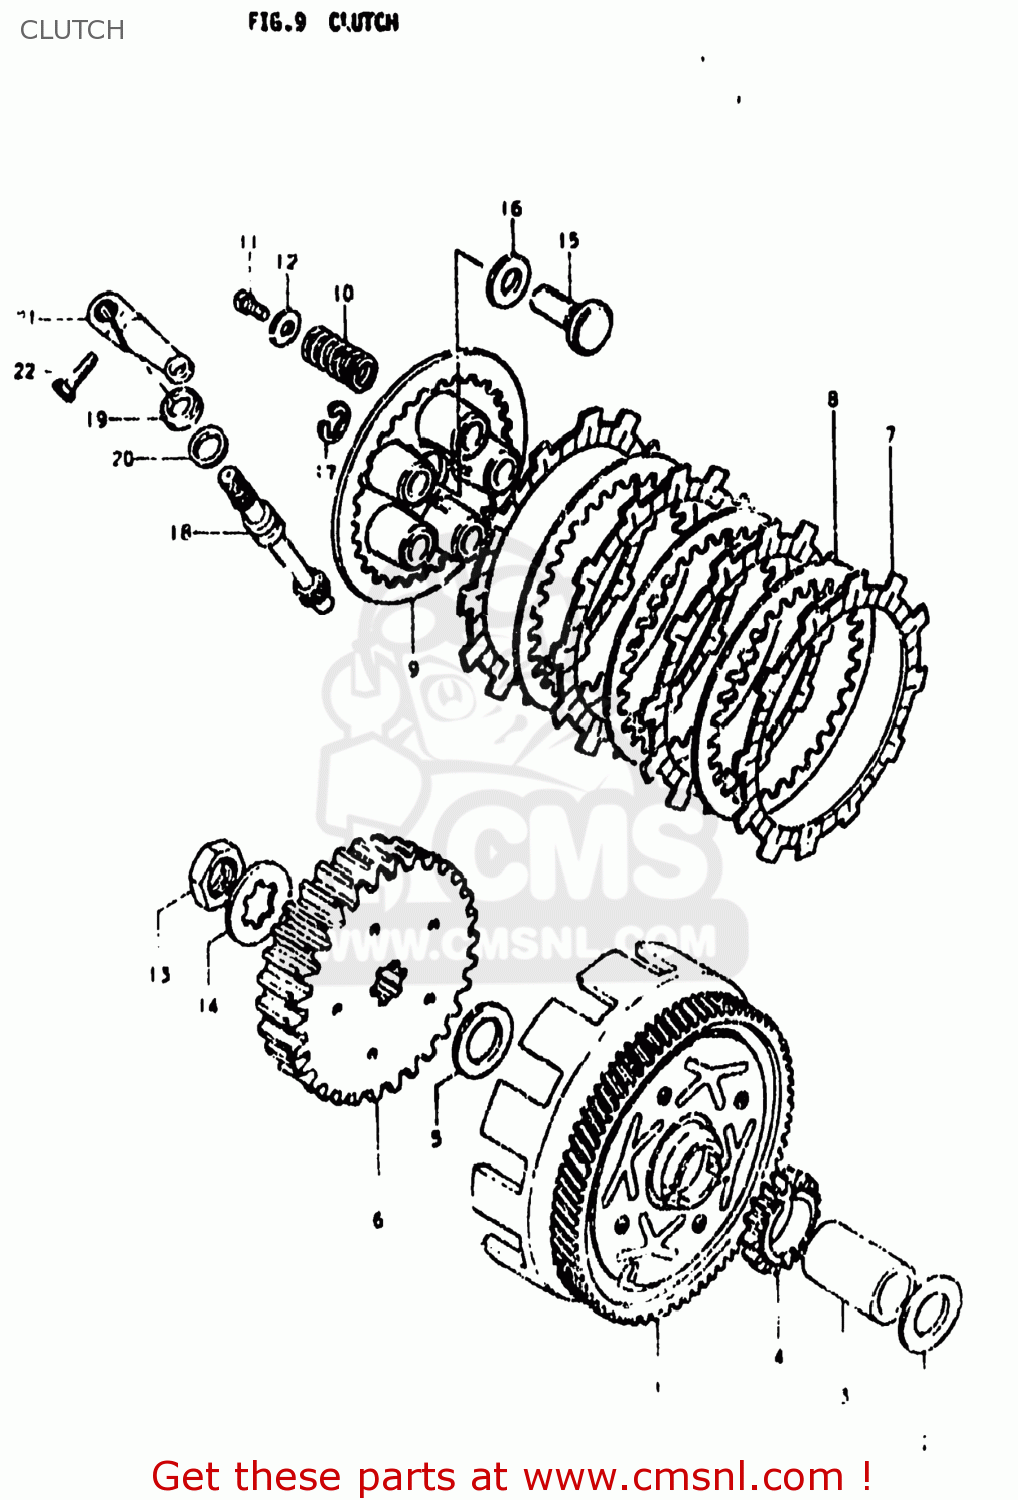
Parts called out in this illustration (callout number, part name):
1	GEAR ASSY,PRI DRIVEN(NT:73)
2	WASHER,THRUST
3	SPACER
4	GEAR,KICK STARTER DRIVE
5	WASHER
6	HUB,CLUTCH SLEEVE
7	PLATE,CLUTCH DRIVE
8	PLATE,CLUTCH DRIVEN (NAS)
9	DISC,CLUTCH PRESSURE
10	SPRING
11	BOLT(5X16)
12	WASHER (5.5X16X1.2)
13	NUT
14	WASHER,LOCK
15	RACK,CLUTCH RELEASE
16	BEARING(10X22X2.8)
17	E RING 8MM
18	PINION,CLUTCH RELEASE
19	OIL SEAL
20	WASHER (12X17X1)
21	ARM,CLUTCH RELEASE
22	BOLT, UPPER
